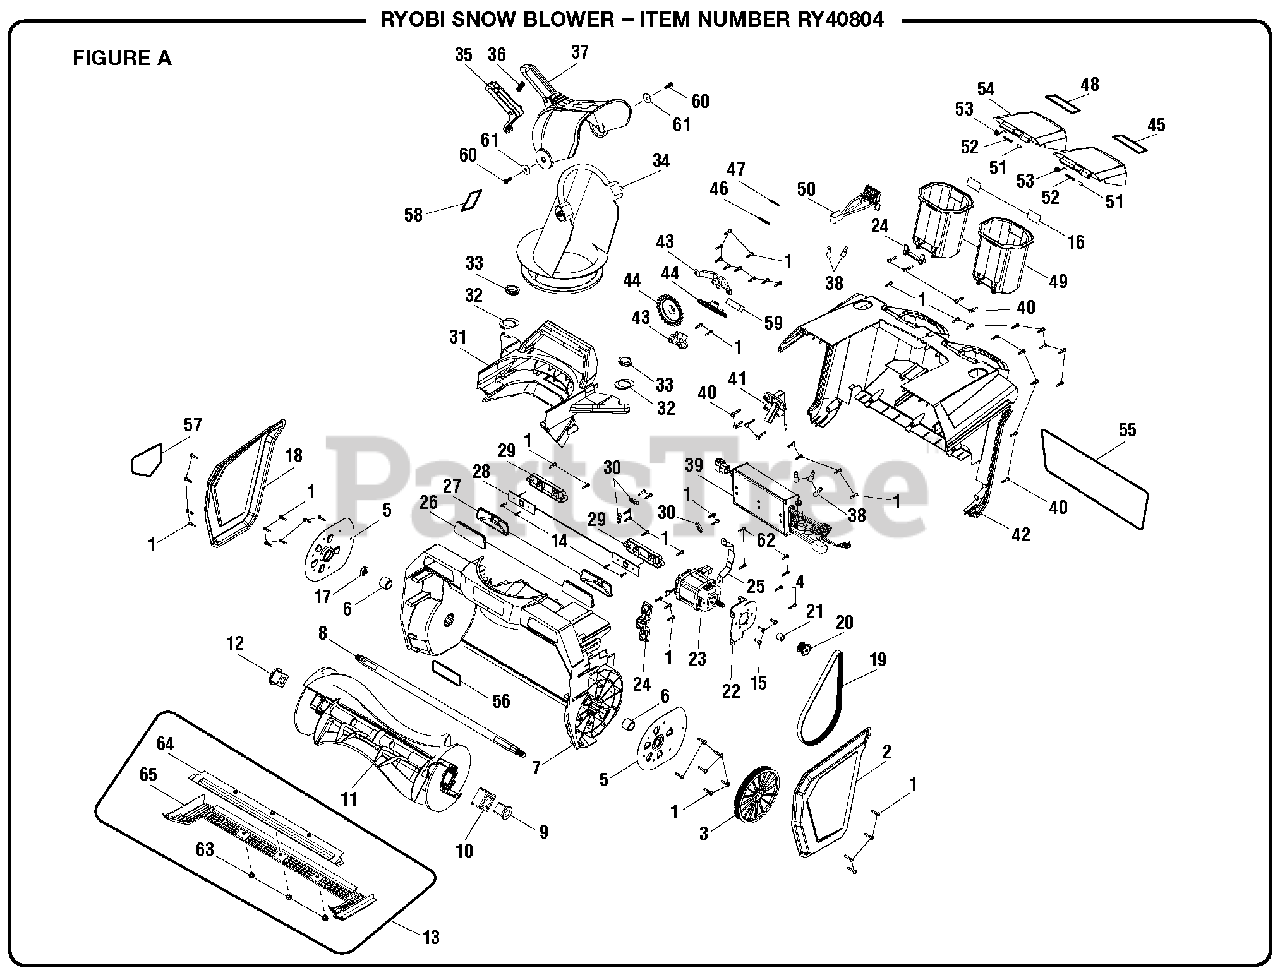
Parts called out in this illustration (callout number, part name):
1	Screw (4 x 18 mm, T15 Torx Pan Hd.)
2	Left Side Cover
4	Screw (M4-18 x 30 mm, T15 Torx Soc. Hd.)
5	Bearing Plate w/Bearing Assembly
7	Front Housing Assembly
8	Auger Shaft
9	Left Drive Block
10	Connect Plate
12	Right Drive Block
13	Scraper Blade Assembly
14	Screw (M3-24 x 8 mm, Pan Hd.)
15	Screw w/Washer (M5 x 8 mm, Pan Hd.)
16	Battery Temperature Label
17	Hex Nut (5/16 in.)
18	Right Cover
19	V-Belt (Type 5EPJ568)
20	Drive Pulley
21	Motor Bushing
22	Motor Locating Plate
24	Motor Support & Terminal Holder Assembly
25	Motor Plate
26	Headlight Lens
27	Reflector
28	LED Light Plate Assembly (Set of 2)
29	Fixing Plate (LED Lens)
30	Cord Clamp
31	Carry Handle
33	Rubber Bushing
35	Nozzle Adjustment Handle
36	Compression Spring
37	Chute Nozzle
38	Wire Connector
39	Brushless Motor Controller
40	Screw (M4 x 20 mm, T20 Torx Pan Hd.)
41	Fixing Plate (Chute Rod)
42	Rear Housing
43	Gear Support Assembly
44	Gear Assembly
45	On-Board Storage Label
46	Washer (ID 17.5 x OD24 x 1t)
48	In-Use Label
49	Battery Carriage
50	Battery Holder Assembly
52	Compression Spring
53	Torsion Spring
54	Battery Cover
55	Data/Warning Label
56	Front Logo Label
57	No Hands/Feet Danger Label
58	Chute Icon Label
59	Rubber Plate
60	Screw (M4 x 12 mm, Pan Hd.)
61	Washer (ID5.2 x OD16 x 1.5t)
62	Screw (M5 x 25 mm, T20 Torx Pan Hd.)
63	Screw (1/4-20 x 3/8 in., T30 Torx Pan Hd.)
64	Scraper Blade (Metal)
65	Scraper Blade Cover (Plastic)
